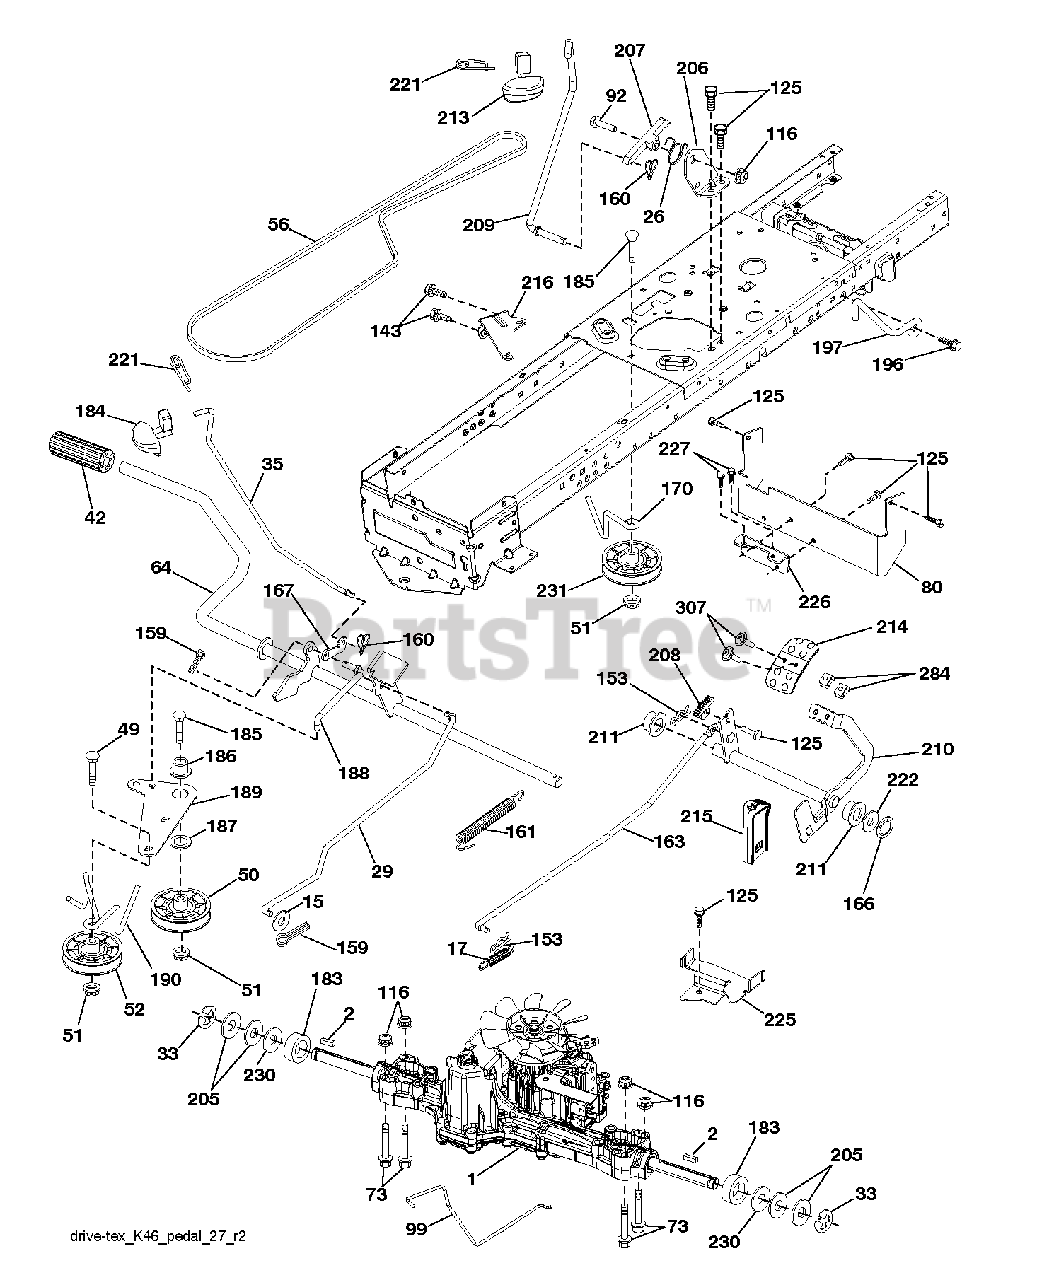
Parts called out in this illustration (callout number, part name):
2	SQUARE KEY
15	WASHER
17	SPRING.BRAKE.K46.GREEN
26	SPRING.RETURN.CRUISE
29	ROD.BRAKE.K46
35	ROD.BRAKE.PARTK.HUSQ.TEX
42	PEDAL COVER T
50	IDLER.FLAT.910.OFFSET
51	NUT LOCK FLG 3/8-16 UNC
52	IDLER.V-GROOVE.910.OFFSET
56	V-BELT.MOWER.92.40.42/K46
64	SHAFT.ASM.PEDAL.BRK.CNTR
80	STRAP.TORQUE.K46.K57R.TT
92	BOLT
99	ROD.SPRING.BYPASS.K46.LT.Z
116	NUT LOCK HEX FLANGE 5/16-18
125	SCREW
143	SCREW LT
153	RETAINER M
159	COTTER PIN
160	RETAINER CLIP
161	SPRING, RETURN LT
163	ROD.CONTROL.PEDAL.K46
166	NUT.PUSH.625
167	LATCH.BRAKE.SPRING
170	KEEPER.CENTER SPAN.1.688
183	SPACER AXLE
184	RB HANDLE.PARKG.BRK.HUS/PRED
186	SPACER.RETAINER
187	WASHER 12/32X2X10GA
188	RP LINK.CLUTCH.GROUND.DRIVE
189	BELLCRANK.GROUND.DRIVE.TEX.
190	KEEPER.BELLCRANK.DRIVE
196	SCREW 3/8-16X1
197	LINK.CLUTCH.ANIT-ROTAT
206	BRKT.MOUNT.LATCH.CRUIS
207	LATCH.CONTROL.CRUISE
208	GEAR.SECTOR.CONTROL.CR
209	ROD.CONTROL.CRUISE.GT.
210	ROCKER.ASM.PEDAL.CONTR
211	BEARING.NYLON
213	KNOB.CONTROL.CRUSIE.HU
214	PEDAL.FORWARD.HUSQVARNA.DEALER
215	PEDAL.REVERSE.TEX.GT.4
216	BRACKET.PULLEY.IDLER.W/TEX
221	RETAINER.SPRING.CLIP.H
222	WASHER 21/32 X 1-1/4 X 10 GA.
225	KEEPER.BELT.TRANSAXLE.K46
226	BRACKET.MOUNT.TORQUE.K46.TLT
227	SCREW
230	WASHER.HARDENED
231	IDLER.V-GROOVE.1.688.OFFSET
284	NUT.U-CHNL.1/4-20.550DP.350PNL
307	SCREW.MACHINE.CR.1/4-20
